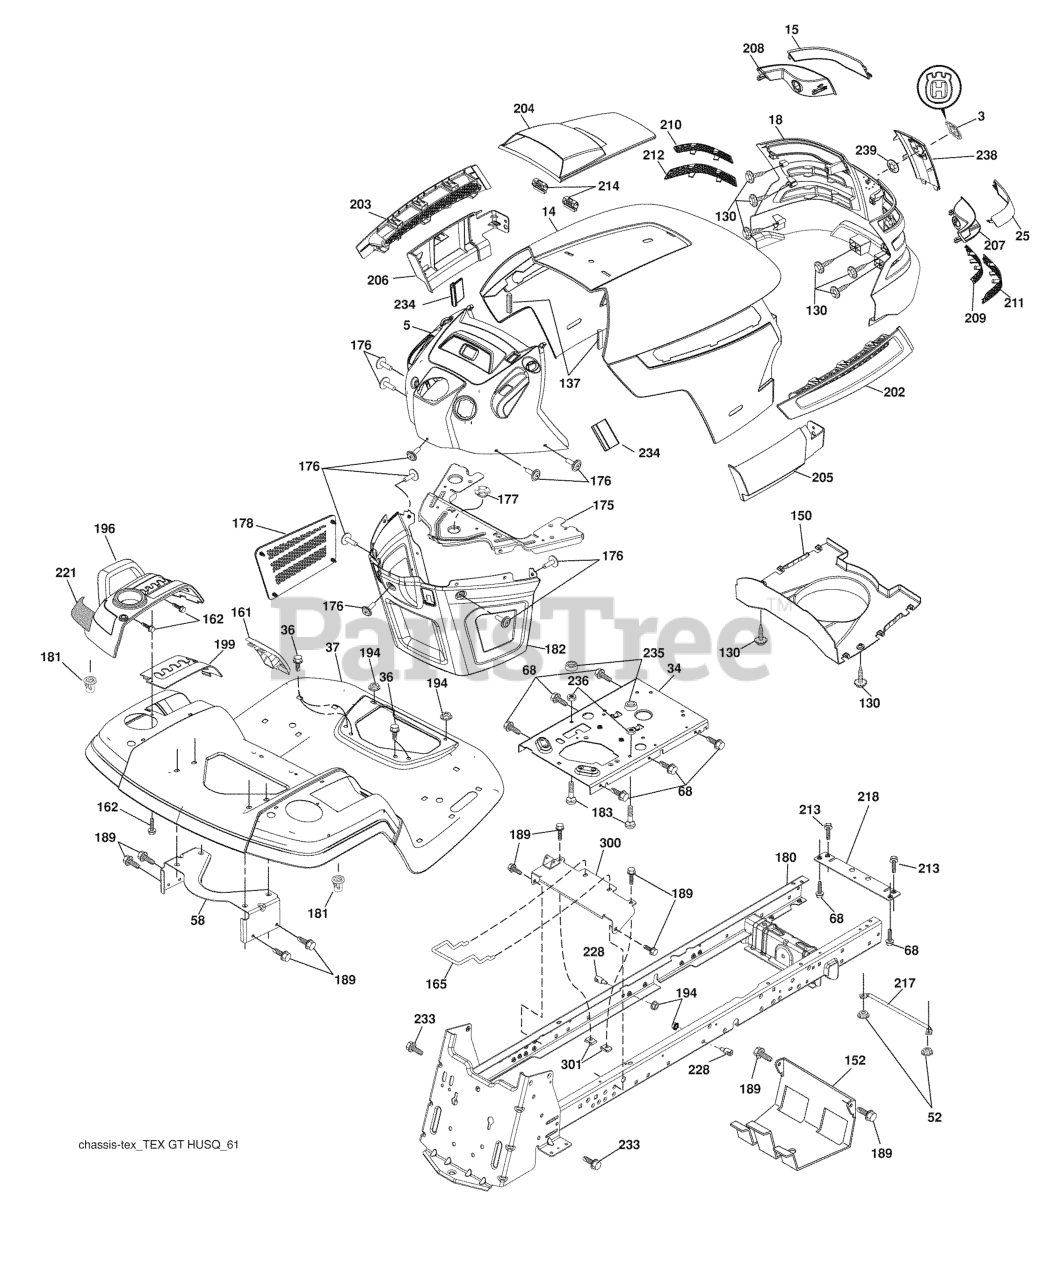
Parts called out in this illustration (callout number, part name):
3	RP LOGO
5	DASH.HUSQ.GT.
14	HOOD
15	LENS.LH.TEX.GT.HUSQ.CL
18	GRILL.ASM.HUSQ.TG/CRD.W/TRIM
25	LENS.RH.TEX.GT.HUSQ.CL
34	PLATE.ENGINE.WELDED.CHASSIS
36	SCREW 5/16"
37	FENDER.PNT.TX.GT.CH/FW.ORANGE
52	LOCKNUT
58	BRKT.SUPPORT.FNDR/TANK
68	Screw 5/16-18 x 1/2
130	SCREW.#10 X 0.750.BOS
137	BUMPER DASH
150	AIR.DUCT.HOOD.TEX.GT.HUSQ
152	SHIELD.BROWNING.W/TEX
161	CONSOLE.FUEL.WINDOW.HU
162	SCREW.HI-LO.CONSOLE
165	SUPPORT.TANK.REAR.B/TE
175	PLATE.CROSSMEMBER.HUSQ
176	SCREW.#10-24X5/8.RN.QU
177	BUSHING, STEERING
178	CARGO.ASM.NET.TXGT.W/C
180	CHASSIS.GT.SLOPED.DRAWBAR.
181	BUSHING.MNT.FEND.CRGO.
182	DASH.LOWER.COMMON.12V.ADAPTOR
183	BOLT.5/16-18X1-1/4 FULL.THREAD
189	SCREW
194	NUT LOCK HEX FLANGE 5/16-18
196	CONSOLE.ASM.DCKLFT.W/RF.HQ.DLR
199	Plate Deck Lift
202	VENT.SIDE.HOOD.HUSQ.RH.GREY
203	VENT.SIDE.HOOD.HUSQ.LH.GRAY
204	HOOD VENT
205	SKIRT.HOOD.SIDE.HUSQ.RH.GREY
206	SKIRT.HOOD.SIDE.HUSQ.LH.GREY
207	BEZEL.RH.TEX.GT.HUSQ
208	BEZEL.LH.TEX.GT.HUSQ
209	INSERT.HEX.GRILL.HUSQ.GREY
210	INSERT.HEX.GRILL.HUSQ.
211	INSERT.HEX.GRILL.HUSQ.
212	INSERT.HEX.GRILL.HUSQ.
213	BOLT
214	CLIP.RETAINER.TINNER.
217	ROD.PIVOT.HOOD
218	X-PIECE.HOOD.STOP.NON/
221	REFLECTOR.LH.TEX GT HU
228	STUD.FASTNER.W/ANTI-ROTATE
233	BOLT.SHOULDER
234	BUMPER.HOOD.TEX.HUSQVARNA
235	SPACER FENDER
236	NUT.CENTERLOCK.5/16-
238	TRIM.HUSQ.TG/CRD.SERVICE
239	NUT PUSH M
300	STRAP.ASM.CROSS.
301	NUT.SPEED.5/16-18
